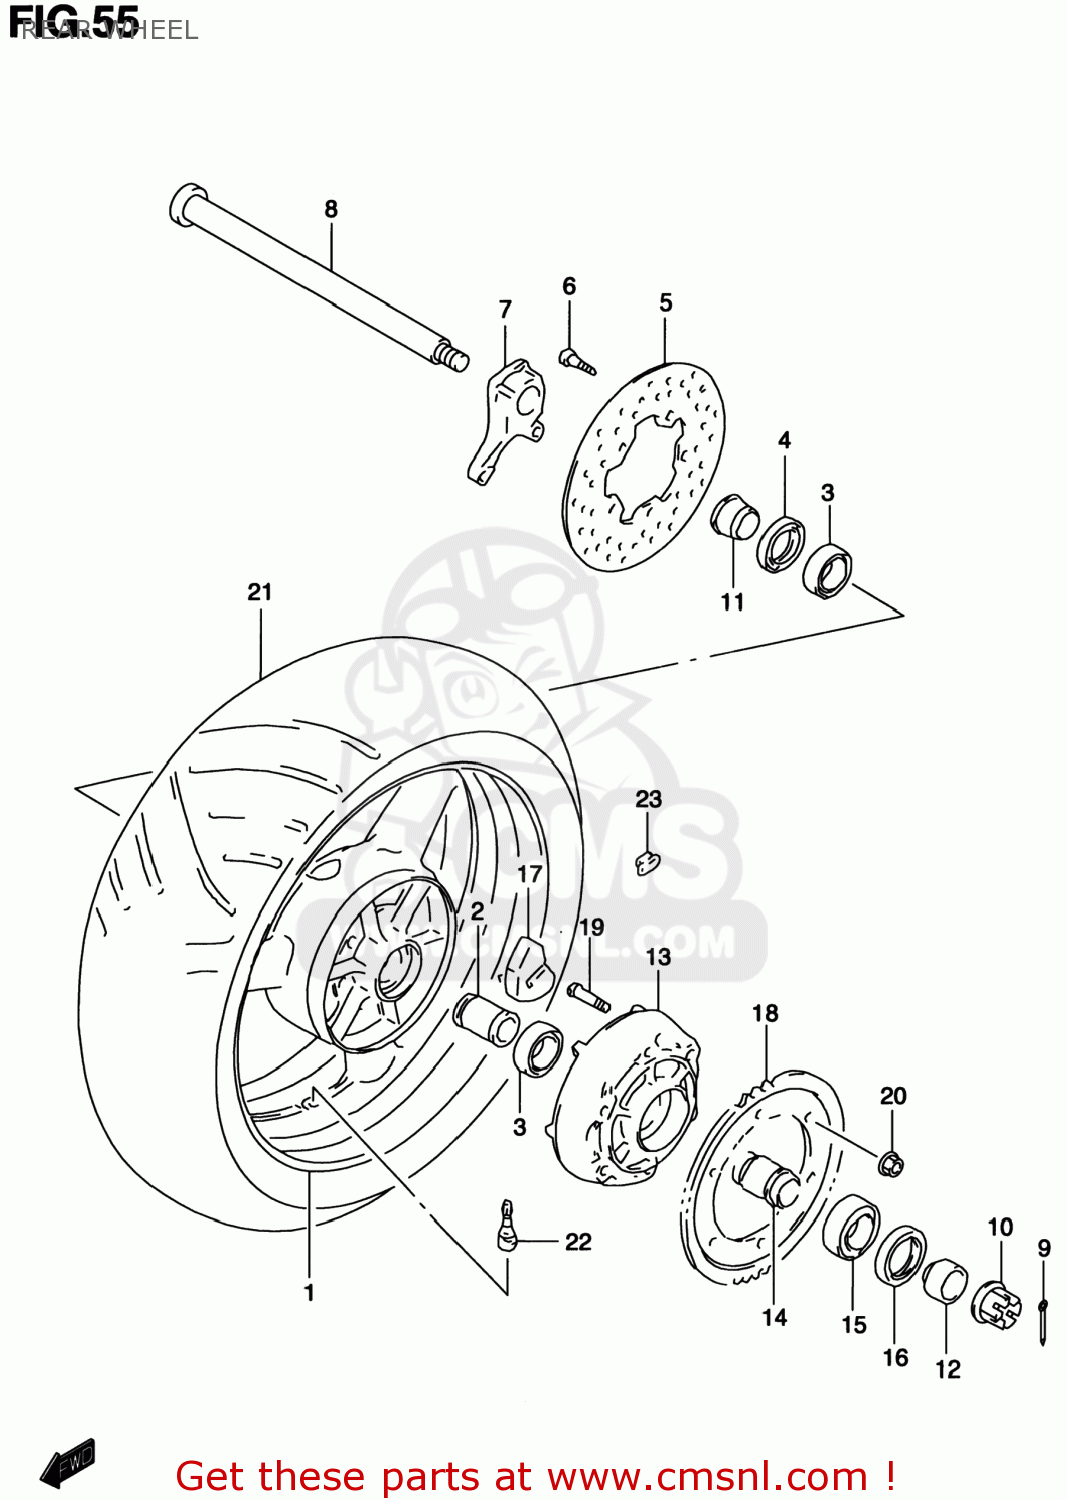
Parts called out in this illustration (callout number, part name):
1	WHEEL,REAR (17XMT6.00)
2	SPACER,RR HUB BEARING
3	BEARING(32X58X13)
4	SEAL,OIL(38X58X7)
5	DISC,RR BRAKE
6	BOLT 8X33
7	BRACKET,RR CALIPER
8	AXLE,RR
9	PIN, COTTER
10	NUT
11	SPACER,RR AXLE,R
12	SPACER,RR AXLE,L
13	DRUM,RR SPROCKET
14	RETAINER,RR SPROCKET DRUM
15	BEARING
16	SEAL,OIL(39X65X7)
17	ABSORBER,RR HUB SHOCK
18	SPROCKET,RR(NT:38-530)
19	BOLT
20	NUT
21	TIRE,REAR 190/50 ZR17
22	VALVE ASSY,WHEEL RIM(TR412)
23	BALANCER,WHEEL (10G)
